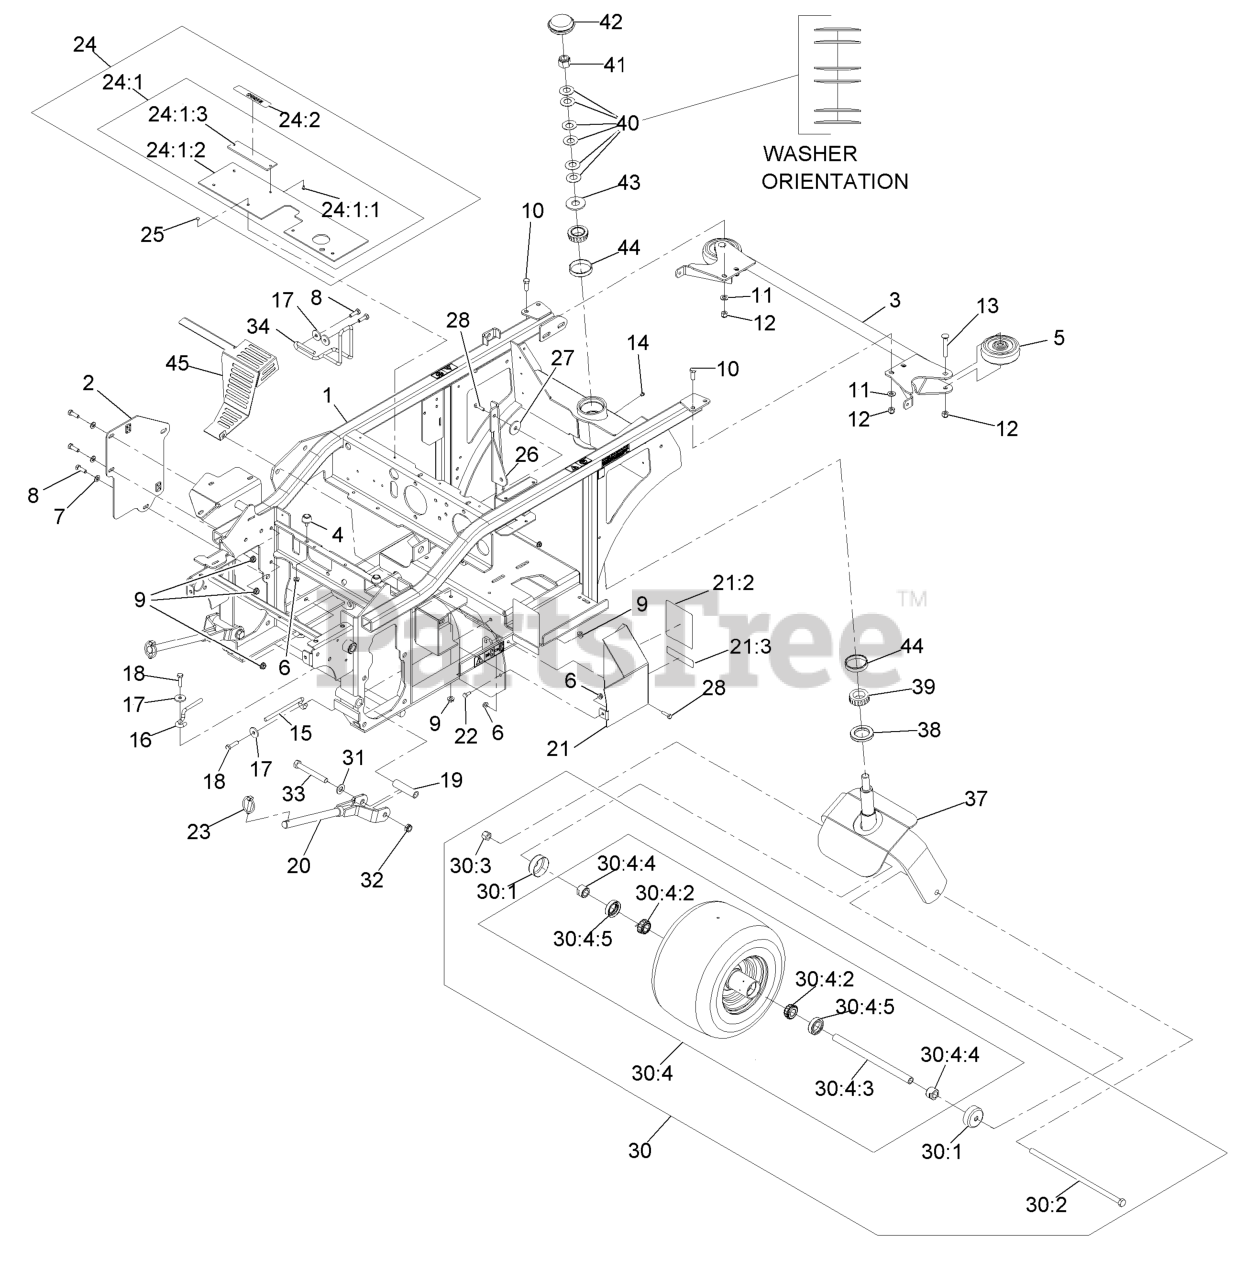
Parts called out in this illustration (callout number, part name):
1	FRAME ASM
2	PLATE-SUPPORT
3	BUMPER-REAR
4	BUMPER-RUBBER
5	ROLLER-BUMPER
7	WASHER-PLAIN
8	SCREW-HH
10	SCREW-HH
11	WASHER-FLAT
12	NUT-LOCK, NI
13	SCREW-CARR
15	GUIDE-BELT
16	GUIDE-BELT
18	SCREW-HH
19	SPACER-WHEEL, SHORT
21	DRIVE SHIELD ASM
21:2	Decal-Belt Routing
21:3	DECAL-WARNING
22	SCREW-HH
23	PIN-LYNCH
24	LIFT SHIELD ASM
24:1	Shield-Lift
24:1:1	RIVET-POP
24:1:3	Plate-Decal
24:2	DECAL-WARNING
25	RIVET-POP
26	BRACE-PTO
28	SCREW-HH
30	REAR CASTER WHEEL ASM
30:1	GUARD-SEAL
30:2	SCREW-HH
30:3	NUT-LOCK, NI
30:4	ASM,WHEEL,TIRE & BRG SP
30:4:2	BEARING-CONE, TAPERED ROLLER
30:4:3	AXLE CASTER ASM
30:4:4	SPACER-NUT
30:4:5	SEAL-CASTER
31	WASHER-FLAT
32	NUT-HEX
33	SCREW-HH
34	GUIDE-BELT
37	FORK-REAR CASTER
38	SEAL-GREASE
39	BEARING-ROLLER, CONE TAPE
40	WASHER-BELLVILLE
41	NUT-LOCK, NI
42	CAP-GREASE
43	WASHER-FLAT
44	CUP-TAPERED, ROLLER BEARI
45	SHIELD-HEAT
